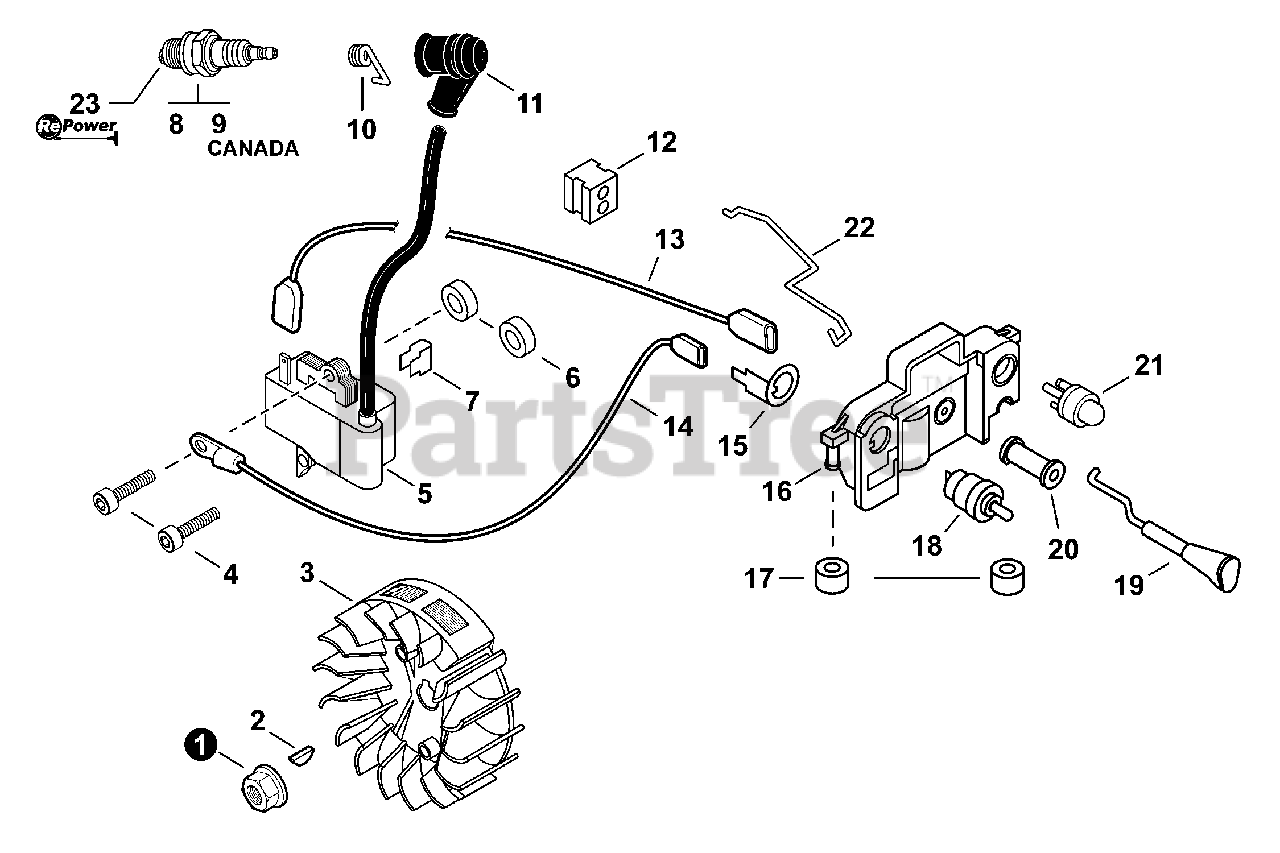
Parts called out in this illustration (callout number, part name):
1	NUT, FLANGE M8
2	KEY, WOODRUFF
3	FLYWHEEL
4	BOLT 5×20
5	COIL, IGNITION
6	WASHER 5.2×12×3
8	SPARK PLUG - BPM8Y
9	SPARK PLUG - BPMR8Y
10	TERMINAL, SPARK PLUG
11	CAP, SPARK PLUG
12	GROMMET, LEAD
13	LEAD - IGNITION L= 172
14	LEAD - GROUND L= 140
15	TERMINAL, GROUND
16	BRACKET, SWITCH
18	SWITCH, ON-OFF
19	ROD, CHOKE
20	GROMMET, CHOKE
21	BULB, PURGE
22	ROD, THROTTLE
23	TUNE-UP KIT - REPOWER
